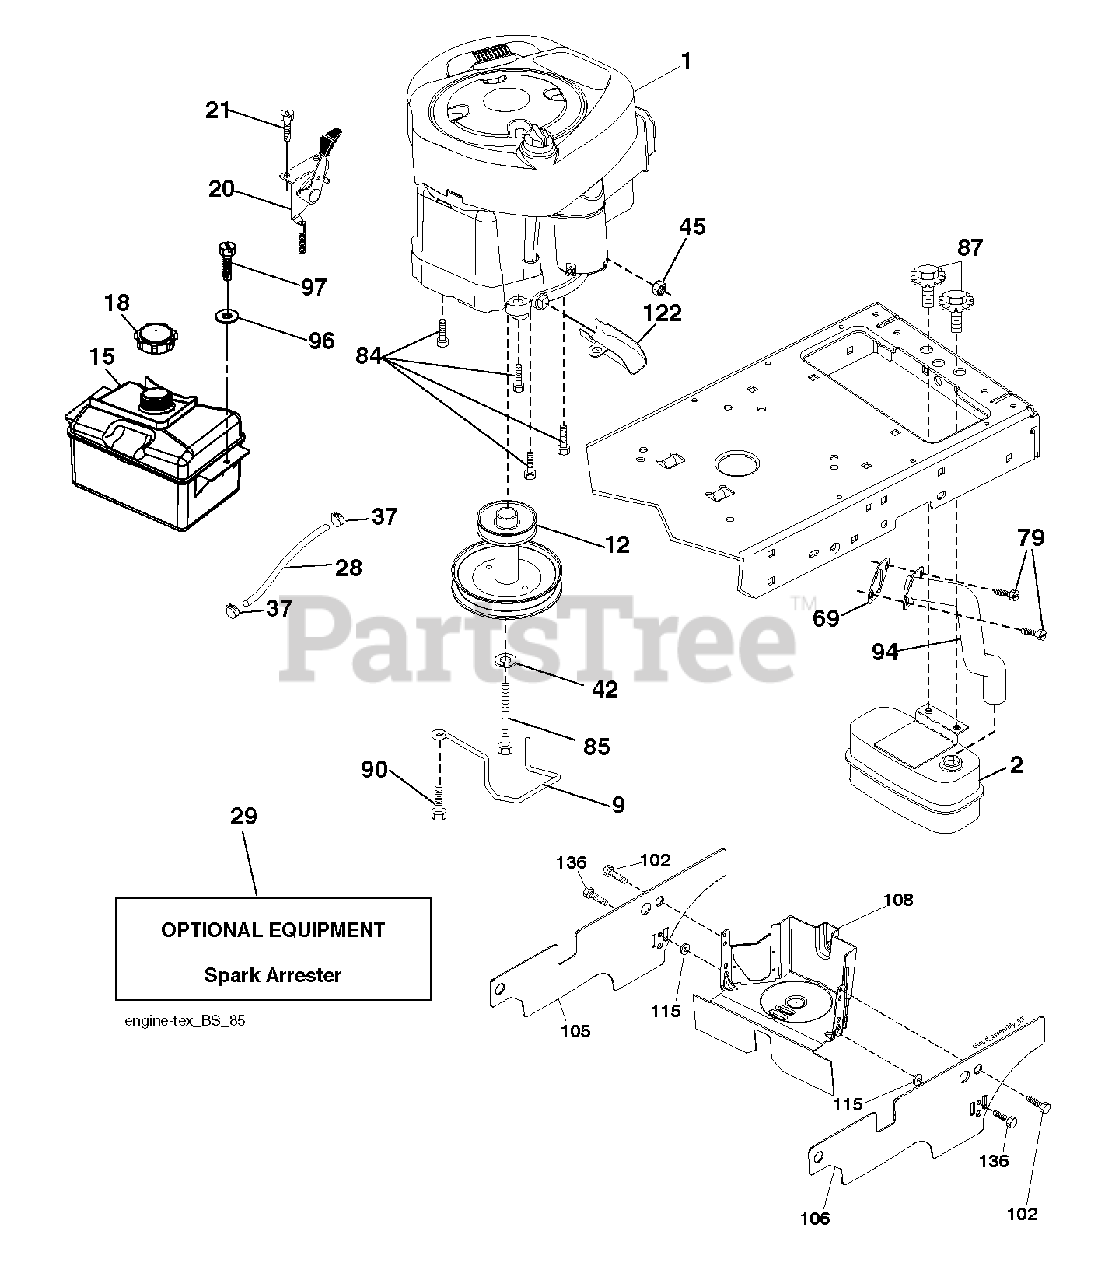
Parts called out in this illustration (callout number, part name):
2	MUFFLER.SINGLE.LRG.BRIGGS.KOHL
9	KEEPER BELT ENGINE
12	ENGINE.PULLEY
15	RP TANK FUEL FRT 1.5 GAL
18	CAP ASM.FUEL.2.25"FR.
20	THROTTLE.COBRA.21".RSTART.BLK
21	SCREW.#10 X 0.750.BOS
28	LINE.FUEL.20
29	KIT.SPARK ARRESTOR 794945 B&S
37	HOSE CLAMP
42	LOCKWASHER
45	NUT
69	GASKET.EXHAUST.KOHLER
79	SCREW.SOCKET HD.5/16-1
84	SCREW.3/8-16
85	BOLT HEX 7/16-20X4-1/4"
87	BOLT, 5/16-18 X 1 3/4
90	SCREW 3/8-16X1
94	EXHAUST.TUBE.B&S.28/31
97	SCREW HEXWSHR 1/4-20X3/4
102	SCREW
105	SHIELD.SIDE.LH.3842"TEX FRENCH
106	SHIELD.SIDE.RH.3842"TEX FRENCH
108	ENGINE COVER
115	PALNUT 1/4
122	EXTENSION DRAIN OIL
136	SCREW.1/4-20X5/8
